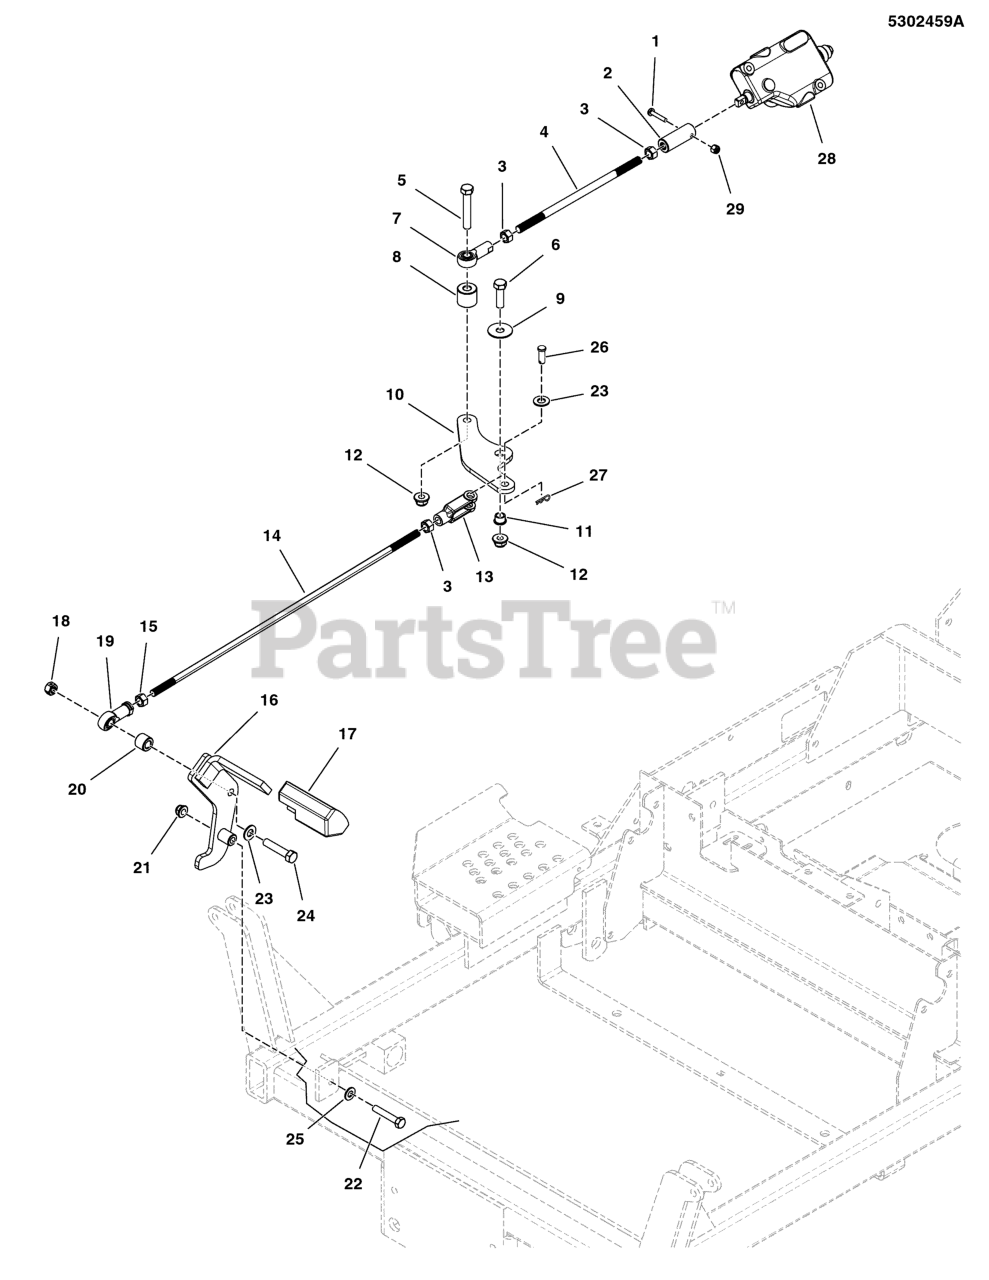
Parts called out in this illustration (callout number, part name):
1	SCREW, #10-24 X 1 RS, CZ
2	SLEEVE, THRD 3/8-24
3	NUT, HEX 3/8-24
4	ROD, LEVER CONNECTING, CZ
5	BOLT, 3/8-16 X 2-1/4" GD5 CZ
6	BOLT, 3/8-16 X 1-1/4" GD5 CZ
7	BALL JOINT, 3/8-24 FEMALE
8	SPACER, .39 X 1.00 X .88, CZ
9	WASHER, 3/8" FENDER
10	PLATE, PIVOTER, IS5100Z - RED
11	BUSHING, FLANGED, 3/8ID X 1/2OD, 5/8OD FLANGE
12	NUT, 3/8-16 HEX NYLOCK FLANGE
13	CLEVIS, 3/8-24 RH, 3/8" PIN HOLE
14	ROD, CRUISE CONTROL, SNP PRO WB
15	NUT, HEX 3/8-24 LH
16	WELD, PEDAL LIFT, IS5100Z - RED
17	PEDAL, Rubber
18	NUT, 3/8-16 HEX SIDE LOCK
19	BALL JOINT, 3/8-24 LH FEMALE
20	SPACER, .39 X .75 X .580
21	NUT, 5/16-18 HEX NYLOCK FLANGE
22	BOLT, 5/16-18 X 1-3/4" GD5
23	WASHER, 3/8 SAE
24	BOLT, 3/8-16 X 1-3/4" GD5 CZ
25	WASHER, 5/16" SAE
26	PIN-CLEVIS, 3/8 X 1 YZ
27	PIN, HAIR, .0915 X 1-7/8
28	VALVE
29	NUT, #10-24 HEX NYLON LOCK
